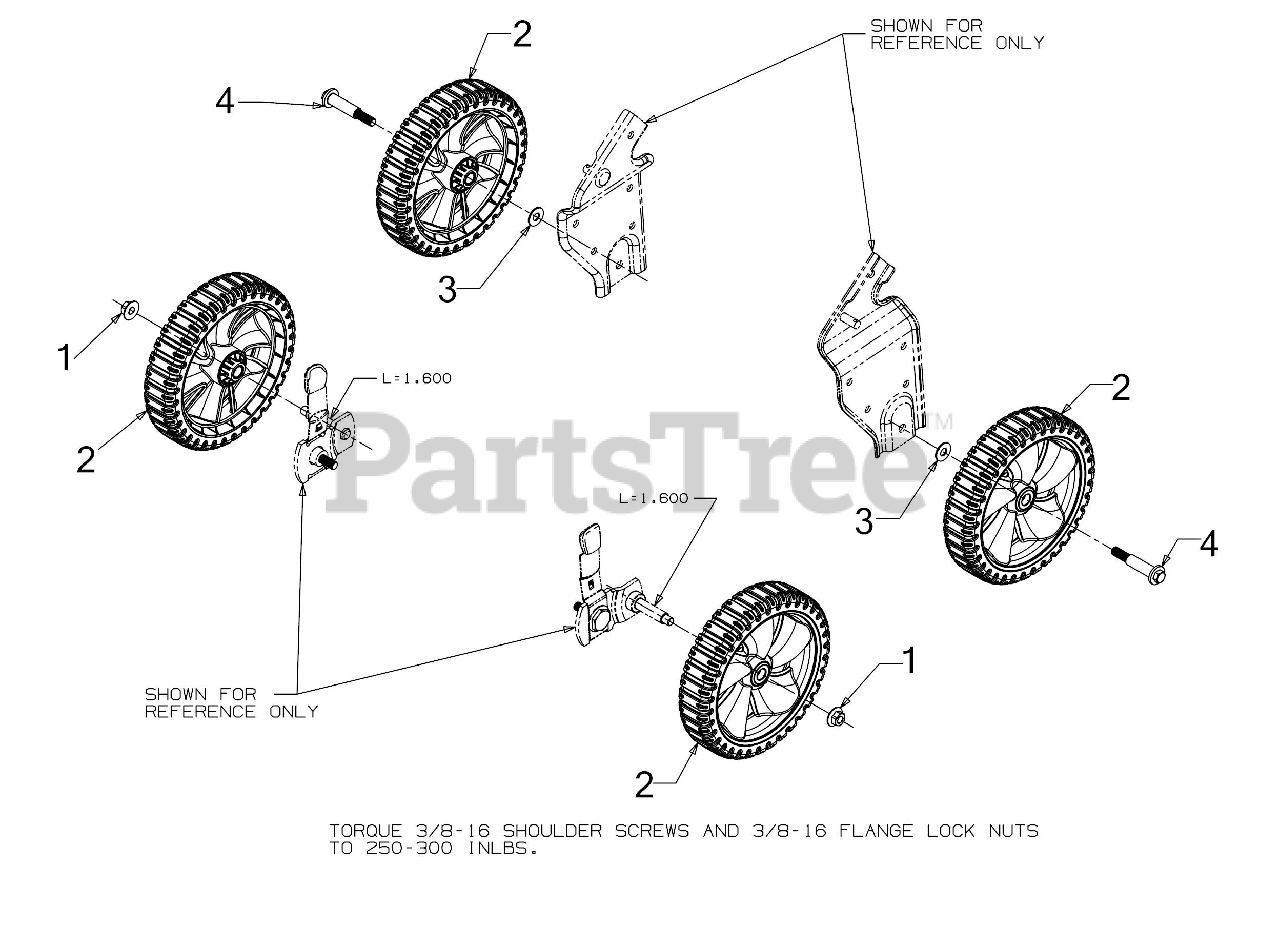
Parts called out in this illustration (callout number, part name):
1	FLANGE LOCK NUT
2	SHOULDER SCREW .496X1.605 3/8-16
3	BELL WASHER .400 ID x .88 x .060
4	WHEEL-8 x 1.8
